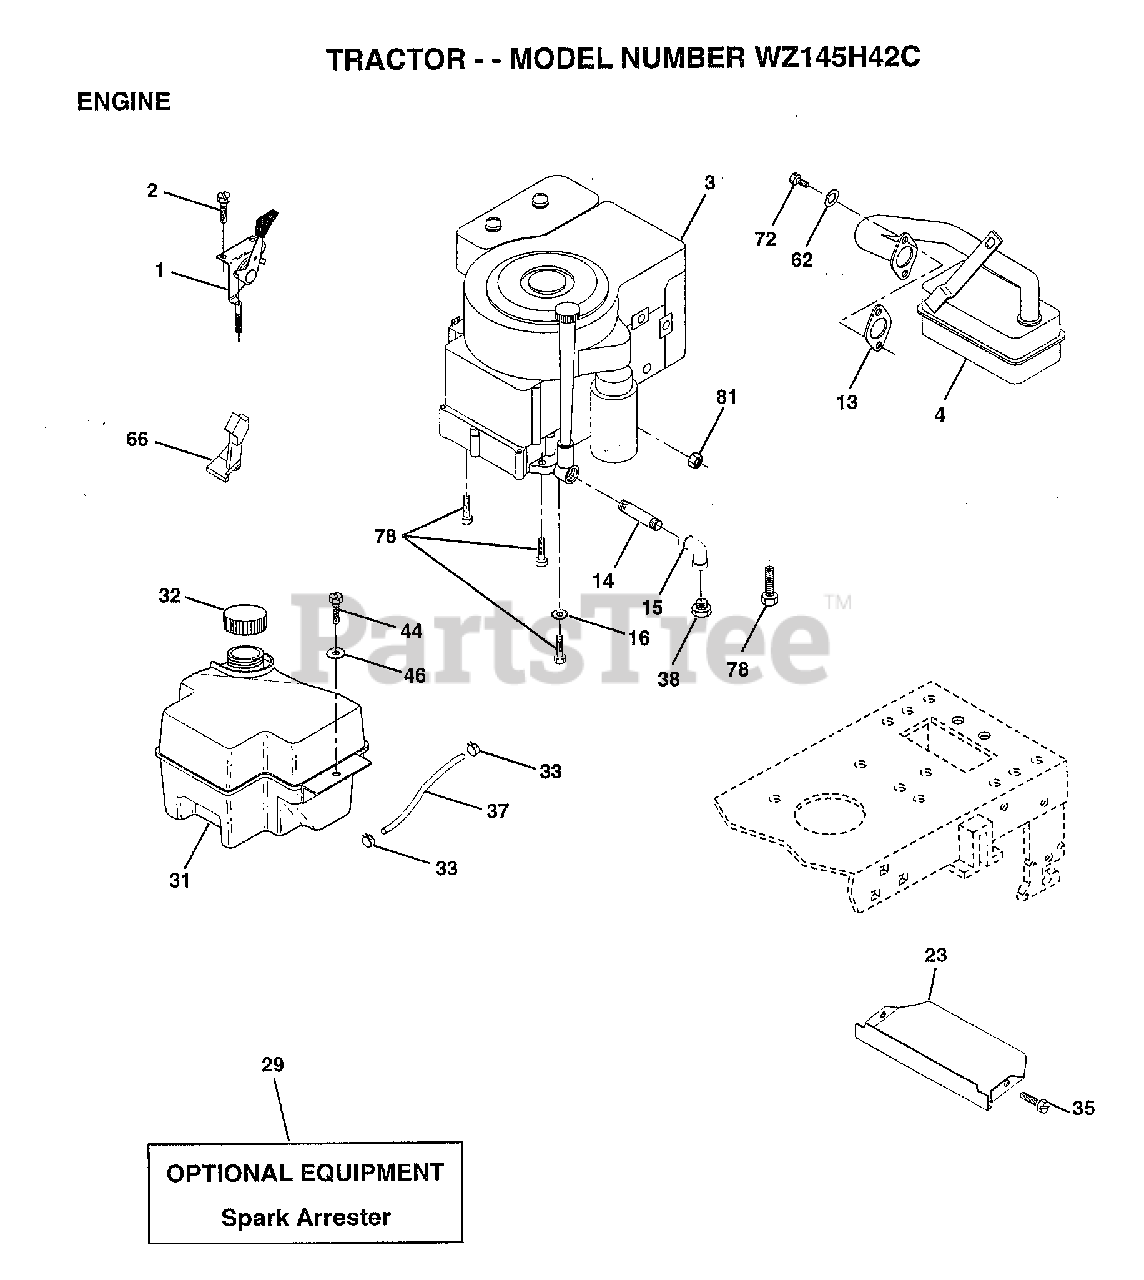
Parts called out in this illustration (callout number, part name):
1	CONTROL.THTL.23.5
2	SCREW LT
4	MUFFLER
14	PIPE NIPPLE
15	ELBOW
16	LOCKWASHER
23	SHIELD.BRN/DBR.GD
31	TANK.FUEL.FRONT.
32	CAP ASM FUEL
33	HOSE CLAMP
35	SCREW
37	LINE FUEL
44	SCREW HEX CRT
46	WASHER
62	LOCKWASHER
66	"STOP,DASH THROTT"
72	SCREW
78	SCREW
81	NUT
